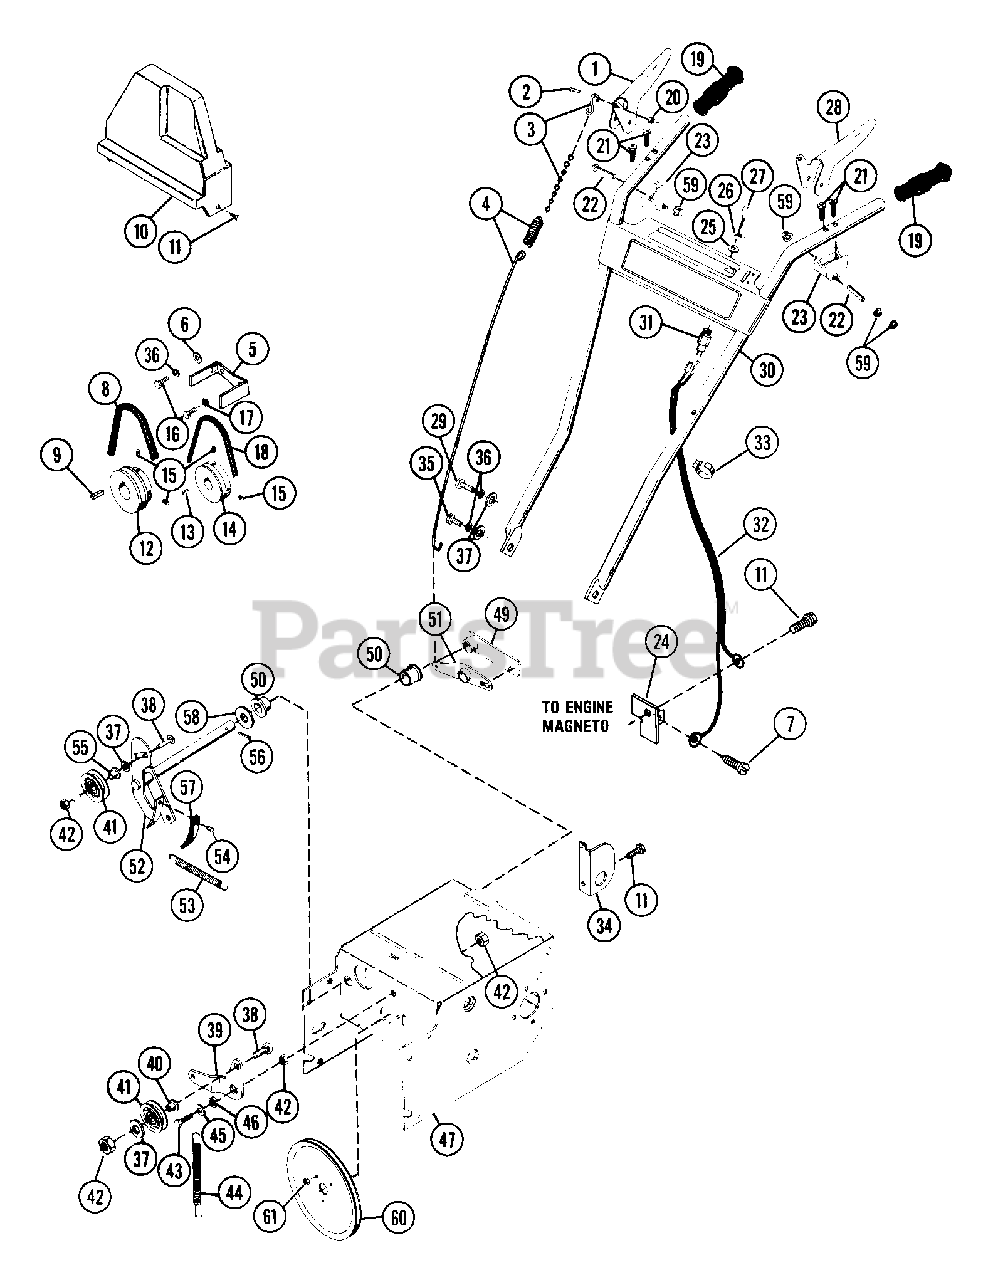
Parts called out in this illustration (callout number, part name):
1	ATTACHMENT CLUTCH HANDLE
2	BLT-HEX .25-20X.50 PL GR2
3	CHAIN & CONNECTOR
4	SG-TENS .080X.25X31.6 WLD 35
5	BELT FINGER
6	WSHR-FL-STL .380X.875X.179 PL
7	SCR-TAP 8-15X.38 CR RH A
8	V-BELT, 4L-COGGED
9	KEY-SQ .188X1.0X.188 SAE 8630
10	BELT COVER
11	BLT-SERHFWH .25-20X.50 PL
12	ENGINE SHEAVE
13	KEY-WDRF .125X.625X.250 SAE5
14	SHEAVE CAMSHAFT
15	SCR-SET .32-18X.38 SKHCUPNL OH
16	BLT-HEX .31-24X.75 PL GR5
17	WSHR-LK .312X.097 PL HVY
18	V-BELT, 3L-COGGED
19	GRIP
20	NUT-LK-CTR .250-20 PL
21	SCR-TAP 12-14X1.50 CROVH PL BT
23	HANDLE PIVOT
24	REMOTE STOP TERMINAL BLOCK
25	WSHR-LK-INT .625X.045 PL
26	NUT .625-32 ALUM
27	KEYS
28	TRACTION CLUTCH HANDLE WITH DE
29	BLT-HEX .31-18X1.50 PL GR2
30	HANDLEBAR
31	SWITCH & KEY SET ASSEMBLY
32	SHORTING WIRE
33	CONDUIT CLAMP 2 WIRE
34	CLUTCH BRACKET GUARD
35	BLT-HEX .31-18X.75 PL GR2
36	WSHR-LK .313X.093 MED HICLR
37	WSHR-FL-STL .38X.875X.083 PL
38	BLT-RDHDSQNK .31-18X1.25 SHTPL
39	IDLER ARM
40	BSHG, FLG .325X.499X.26X.88
41	IDLER
42	NUT-LK .312-18 GR A PL
43	BLT-HEX .31-18X.63 PL GR 2
44	SG-TENS .047X.44X3.37 WLD 1.47
45	WSHR-FL-STL .344X1.375X.075 PL
46	SPACER BUSHING .5 X .32 X .163
49	LEVER CLUTCH
50	BSHG-FLG.500X.625X.312X.750NY
52	BRAKE CLUTCH ASSY
53	SG-TENS .062X.55X5.0
54	RVT-TBLR .187X.375 OH ST PL
55	SPCR, BRG .315X.50X.688X.281
56	PIN-ROLL .156X.88
57	BRAKE LINING
58	WSHR-FL-STL .531X1.062X.095 PL
59	PUSH NUT, .25
60	PLY-V 8.0 X 1.25 3BLT SALEM
61	NUT-FLG. .312-18 PL
